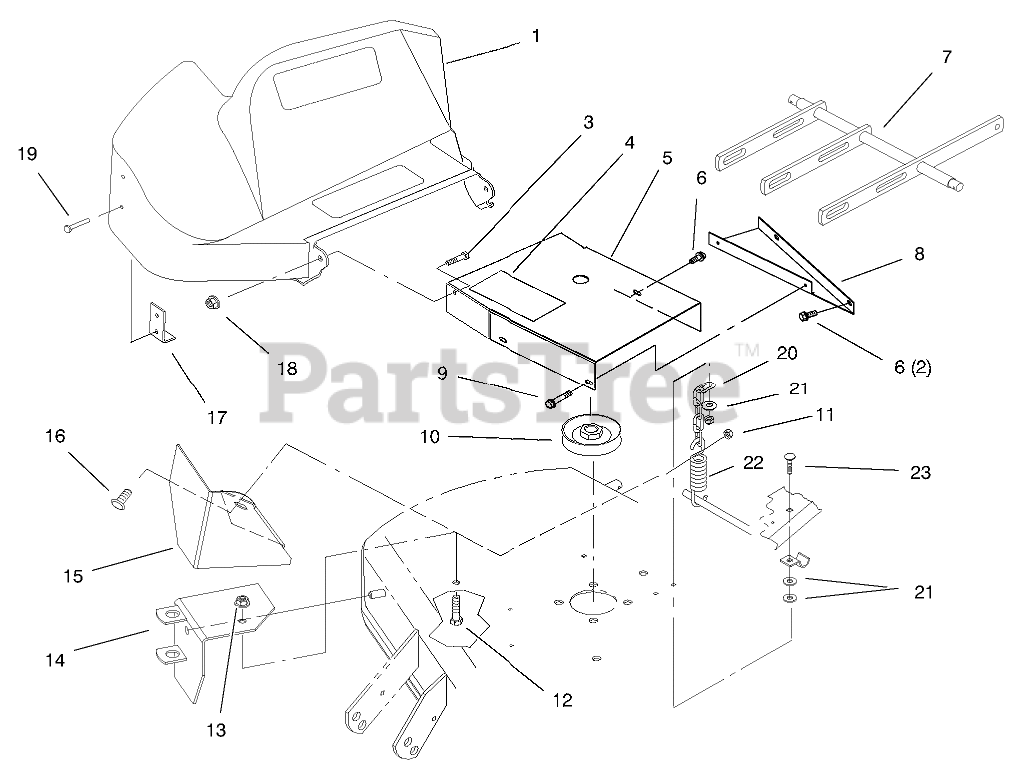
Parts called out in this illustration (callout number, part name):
1	SHIELD-BELT
3	SCREW-HH
4	DECAL-DANGER
5	Inner Shield Assembly (Incl. Ref. #4)
6	SCREW-HHF
7	Bar-Leveler
8	48" ADAPTOR SHIELD B
9	SCREW-HWH
10	PULLEY
11	NUT-LOCK, NI
12	SCREW-HH
13	NUT-HF
14	PIVOT SUPPORT ASM
15	48" DEFLECTOR B
16	SCREW-CARR
17	BRACKET-SUPPORT, SHIELD
18	NUT-LOCK, NI
19	RIVET-POP
20	CHAIN
21	WASHER-FLAT
22	SPRING-EXTENSION
23	SCREW-CARR
